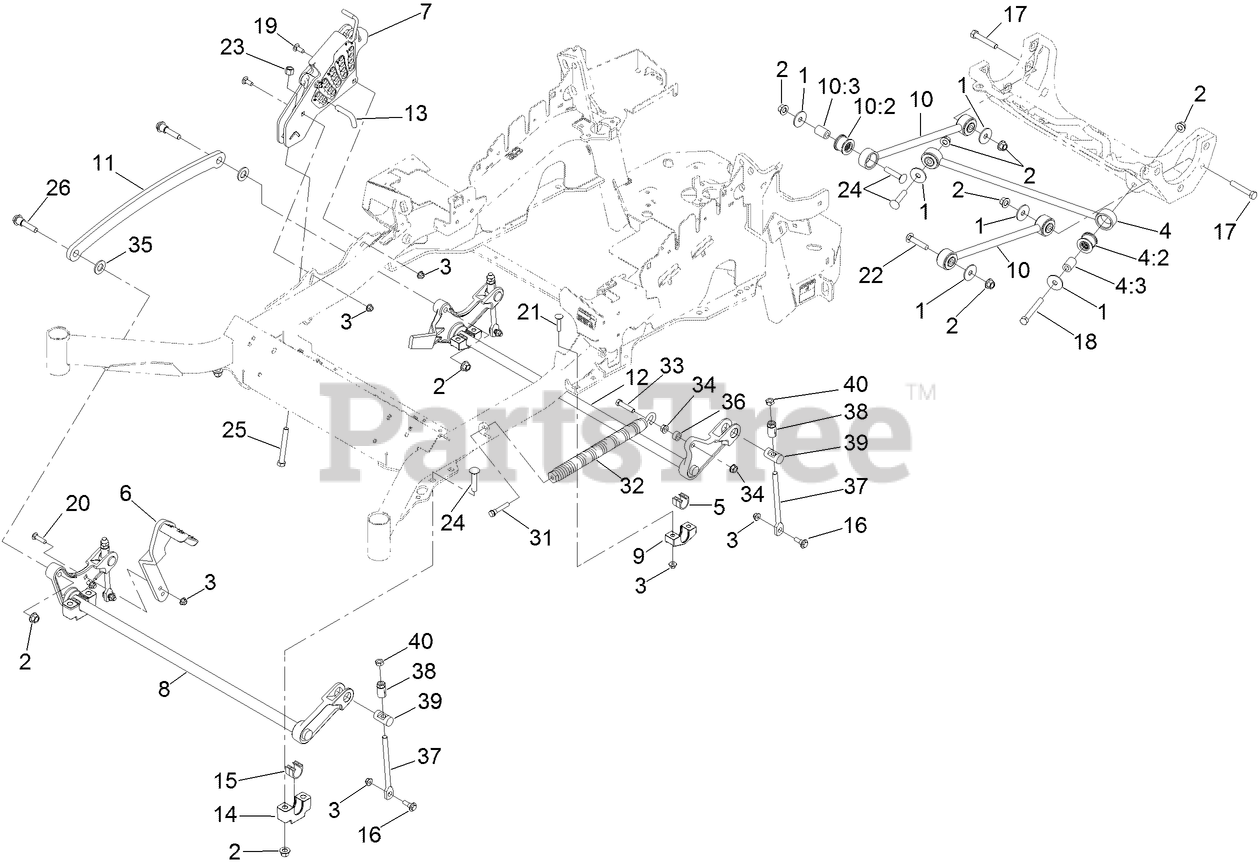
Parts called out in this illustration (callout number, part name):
1	WASHER-THRUST
2	NUT-LOCK
3	NUT-HF, NI
4	PANHARD ROD ASM
4:2	BUSHING-SUSPENSION, RUBBER
4:3	SPACER
5	BEARING-CROSS SHAFT, REAR
6	LEVER-FOOT
7	HEIGHT-OF-CUT ASM
8	DECK LIFT-FRONT
9	SUPPORT-CROSS SHAFT, REAR BEARING
10	DECK STRUT ASM
10:2	BUSHING-SUSPENSION, RUBBER
10:3	SPACER
11	LINK-LIFT, DECK
12	LIFT-DECK, REAR
13	PIN-HOC
14	SUPPORT-CROSS SHAFT, BEARING
15	BEARING-CROSS SHAFT, FRONT
16	SCREW-SHOULDER, HHF
17	SCREW-HH
18	SCREW-HH
19	BOLT-CARR
20	SCREW-CARR
21	SCREW-CARR
22	SCREW-CARR
23	NUT-LOCK, NI
24	BOLT-CARR
25	BOLT-TAP
26	SCREW-HHF, SHOULDER
31	BOLT-SHOULDER
32	SPRING-EXTENSION
33	SCREW-HH
34	NUT-HF
35	WASHER-FLAT
36	SPACER
37	LINK-ADJUSTER, DECK LIFT
38	ADJUSTER-LIFT, DECK
39	TRUNNION
40	NUT-JAM
